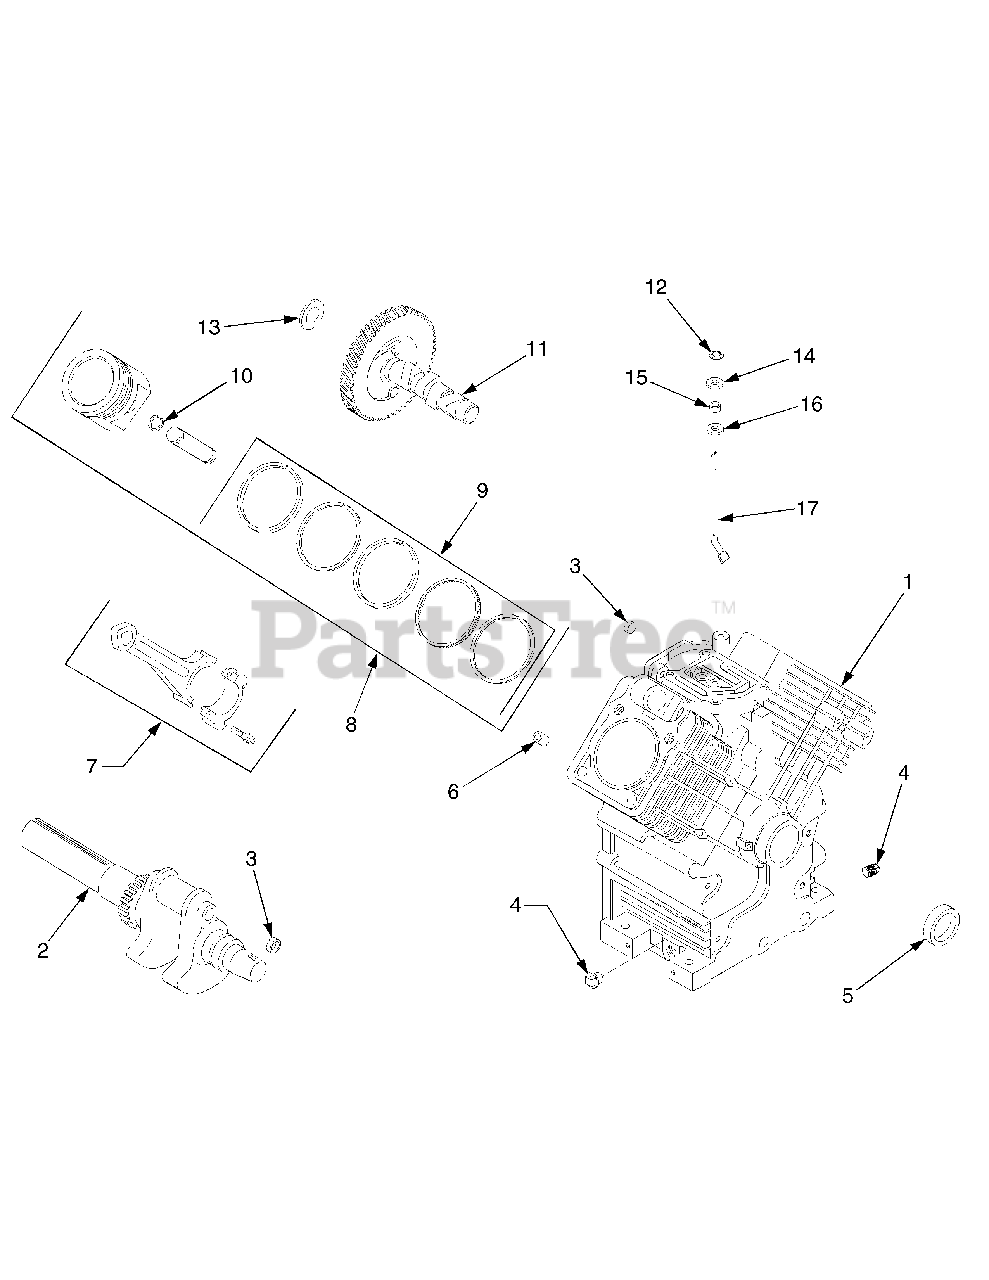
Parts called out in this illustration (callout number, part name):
1	Engine, Complete
2	Crankshaft (Includes 3)
3	Plug, Cup
4	Plug, Hex Head, 3/8 NPTF
5	Seal, Oil
6	Pin, Dowel Locating
7	Rod, Connecting, Std
7	Rod, Connecting, .010
8	Piston w/Ring Set, Std
8	Piston w/Ring Set, .003
8	Piston w/Ring Set, .010
8	Piston w/Ring Set, .020
9	Ring Set, Std & .003
9	Ring Set, Std & .010
9	Ring Set, Std & .020
10	Retainer, Piston Pin
11	Camshaft
12	Ring, Retainer
13	Shim, Camshaft, .0320 red
13	Shim, Camshaft, .0400 black
13	Shim, Camshaft, .0280 white
13	Shim, Camshaft, .0300 blue
13	Shim, Camshaft, .0340 yellow ..
13	Shim, Camshaft, .0360 green ...
13	Shim, Camshaft, .0380 gray
14	Washer, Flat 8mm
15	Seal, Governor Cross Shaft
16	Washer, Plain
17	Shaft, Governor Cross
